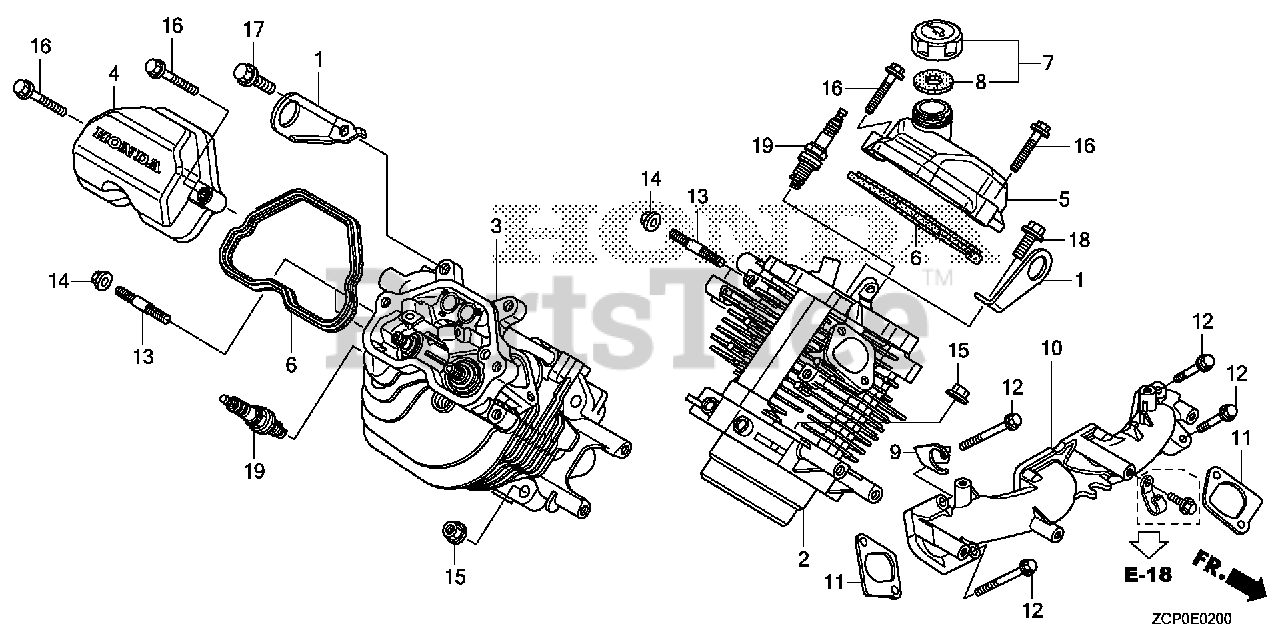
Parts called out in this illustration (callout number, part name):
1	HANGER, ENGINE
2	CYLINDER HEAD (#1)
3	CYLINDER HEAD (#2)
4	COVER, CYLINDER HEAD
5	COVER, CYLINDER HEAD
6	GASKET, HEAD COVER
7	CAP ASSY., OIL FILLER
8	GASKET, OIL FILLER CAP
9	STAY, FUEL TUBE GROMMET
10	MANIFOLD, IN.
11	GASKET, IN. MANIFOLD
12	BOLT, FLANGE (8X55)
13	BOLT, STUD (8X22)
14	NUT, FLANGE (8MM)
15	NUT, FLANGE (10MM)
16	BOLT, FLANGE (6X30)
17	BOLT, FLANGE (8X16)
18	BOLT, FLANGE (8X16)
19	SPARK PLUG (ZFR5F)
